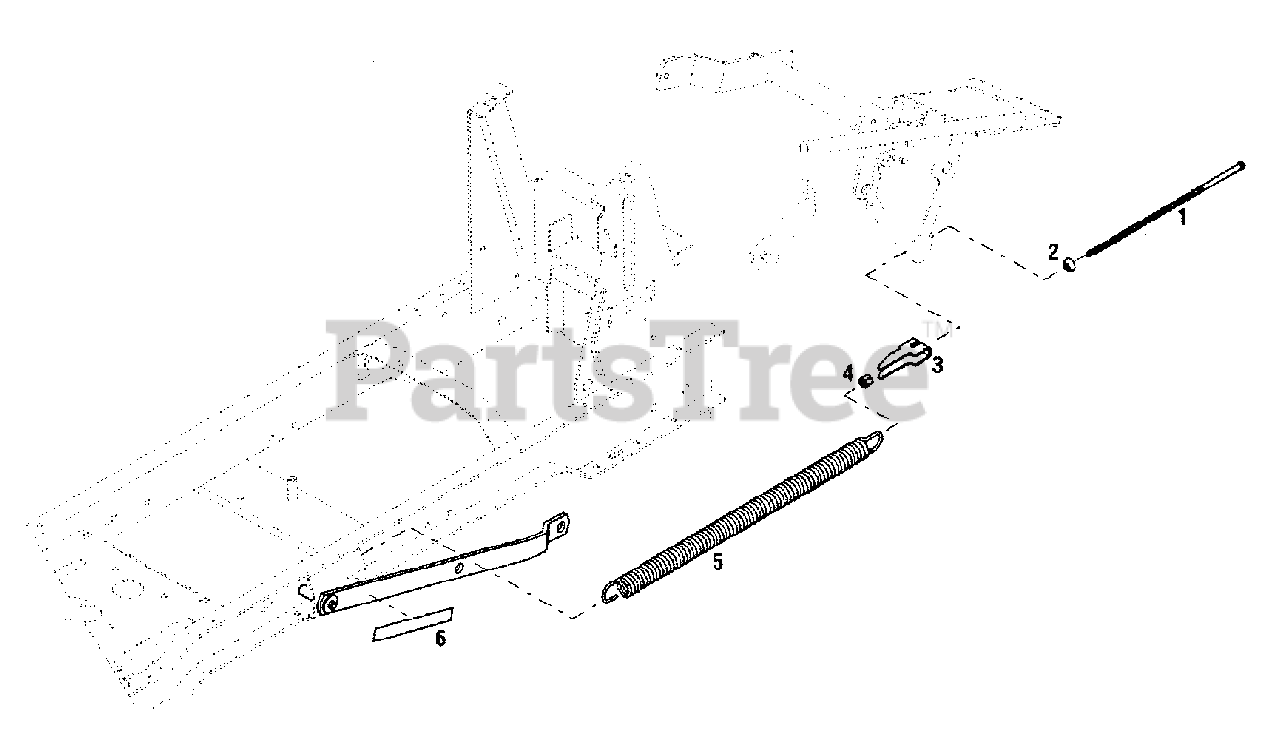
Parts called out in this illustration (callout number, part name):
1	Lift Assist Bolt
2	Spherical Bearing
3	Lift Assist Bracket
4	Special Nut, 5/16-18
5	Lift Assist Spring
6	Warning Decal
